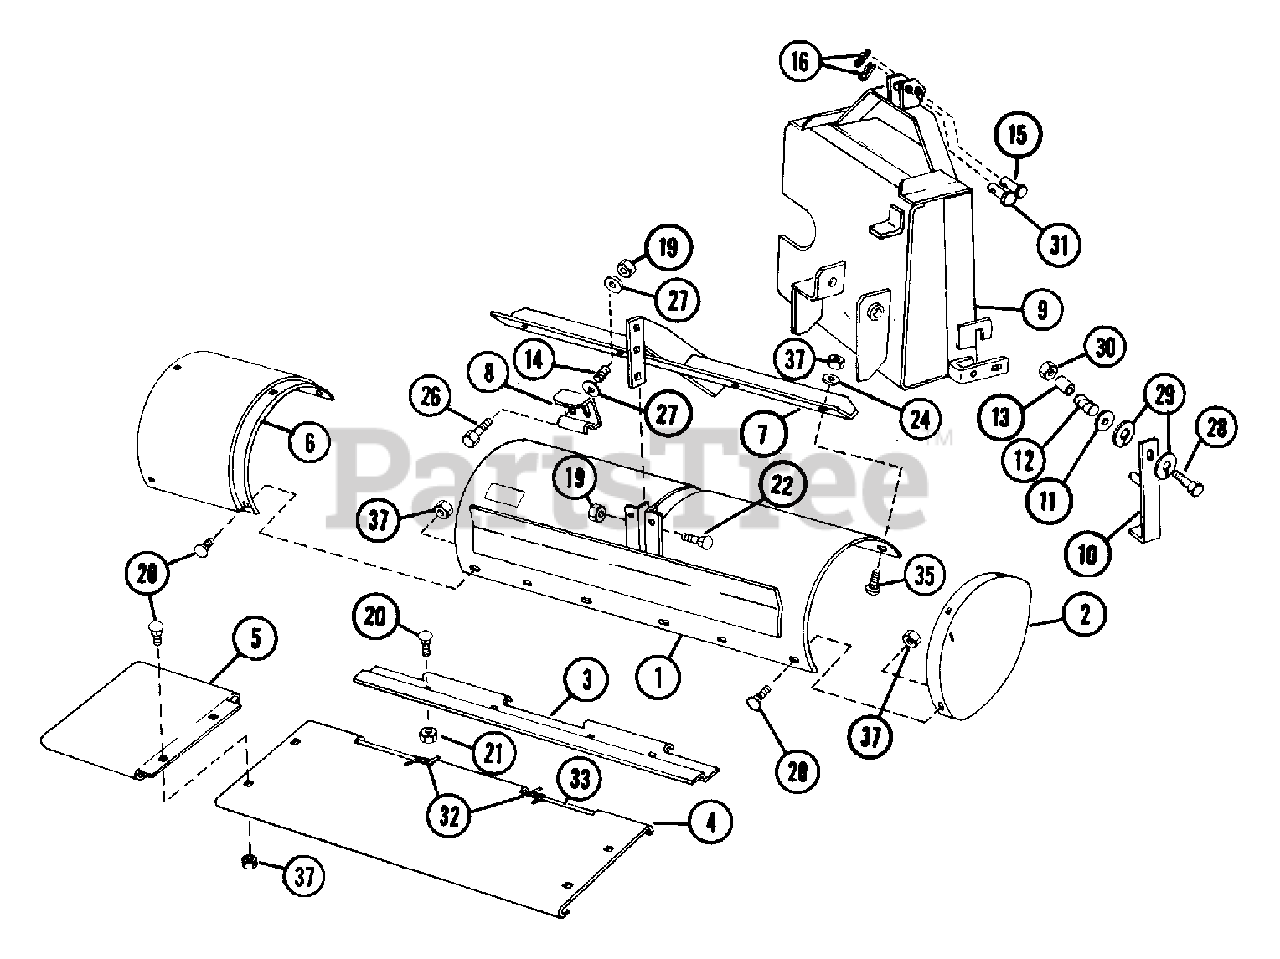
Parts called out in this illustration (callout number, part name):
1	SHROUD ASSEMBLY
2	SHROUD COVER
3	HINGE PLATE
4	LEVELER BLADE
5	BLADE LEVEL EXTENSION
6	SHROUD EXTENSION
7	SHROUD BRACE
9	TILLER FRAME
10	KICK STAND LEG
11	SPACER .406X1.500X.188
12	SG-COMP .70X.68X.68
13	SPACER .384X.500X.625
14	SG-COMP .059X.43X1.00 WLD??
15	CLEVIS PIN
16	PIN-HAIR INT .09X.188 PL
19	NUT-LK TOP .250-20 PL
20	BLT-RDHDSQNK .31-18X.50 GR5 PL
21	NUT-LK .312-18 GR A PL
22	BLT-RDHDSQNK .25-20X.75 GR5PL
24	WSHR-FL-STL.344X.688X.065PL
26	BLT_HEX .25_20X1.75 GR5
27	WSHR-FL-STL.281X.62X.065 PL
28	BLT-HEX .38-16X2.25 GR2
29	WSHR-LK .375X.094 MED PL
30	NUT-HEX .375-16
31	CLEVIS PIN
32	SG-TORS .090X.37X.63
35	BLT-RDHDSQNK.31-18X.75GR5SHTPL
37	NUT-CROWN .312-18 PL
38	WSHR-FL-STL .781X1.250X.059 PL
